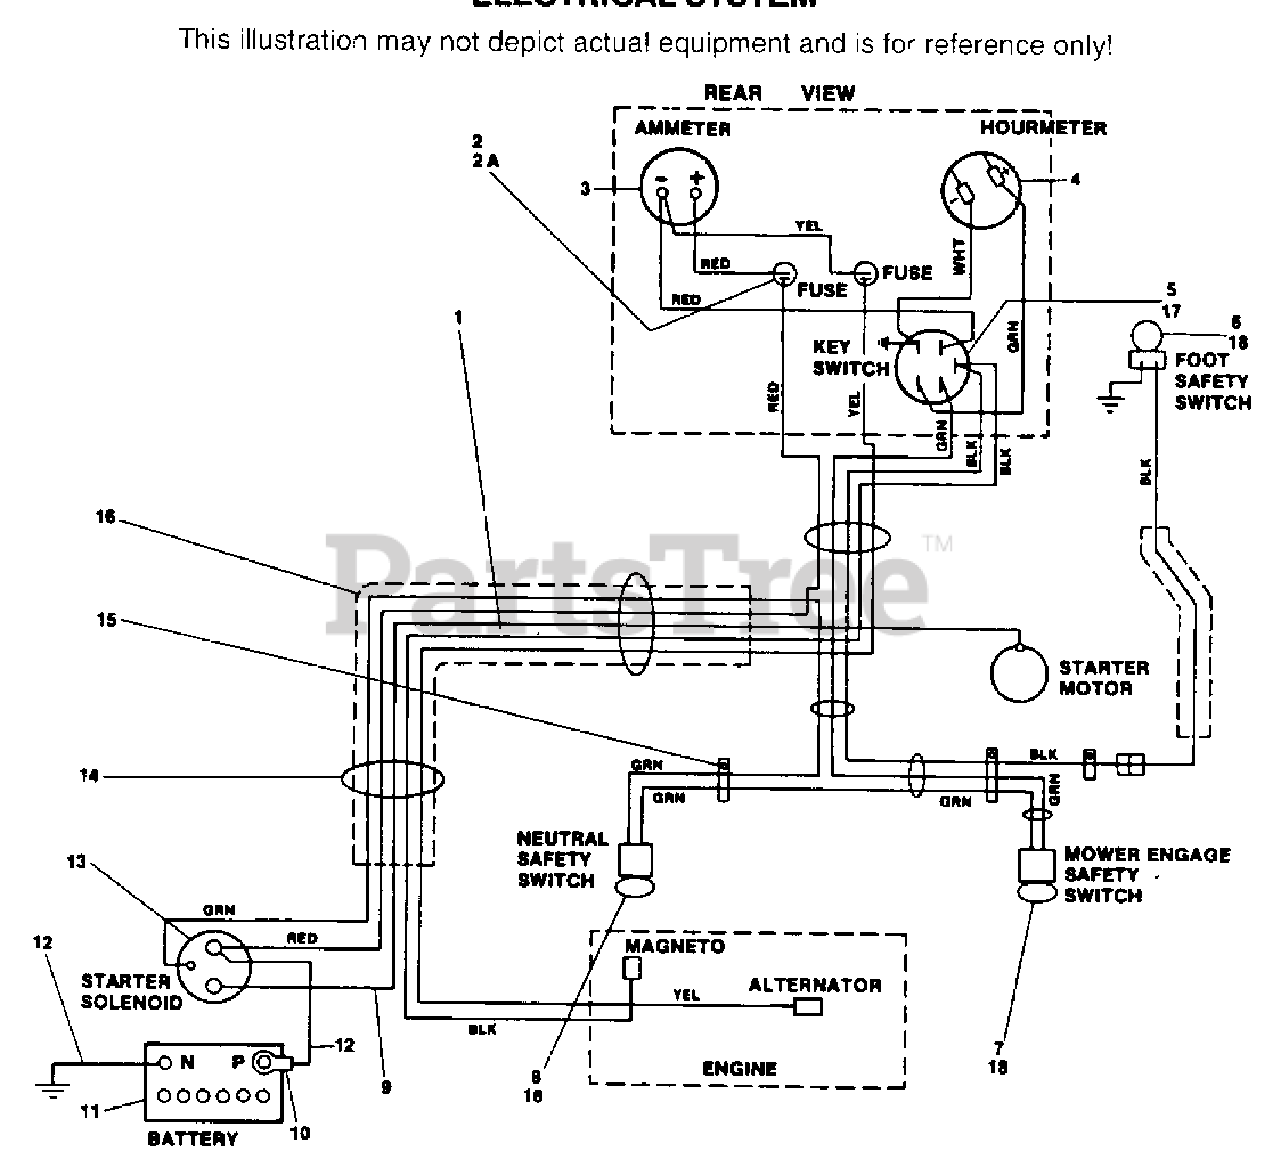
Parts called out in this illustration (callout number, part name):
1	WIRING HARNESS, COMPLETE
2	FUSE HOLDER
2A	FUSE, 20
3	AMMETER
4	HOUR METER
5	KEY SWITCH
6	FOOT SAFETY SWITCH
7	MOWER ENGAGE SAFETY SWITCH
8	NEUTRAL SAFETY SWITCH
9	BATTERY CABLE
10	RUBBER BOOT
11	BATTERY
12	BATTERY CABLE
13	STARTER SOLENOID
14	CABLE TIE
15	CABLE CLAMP
16	PLASTIC CONDUIT
17	CONNECTOR, STARTER SWITCH
18	CONNECTOR, SAFETY SWITCH
